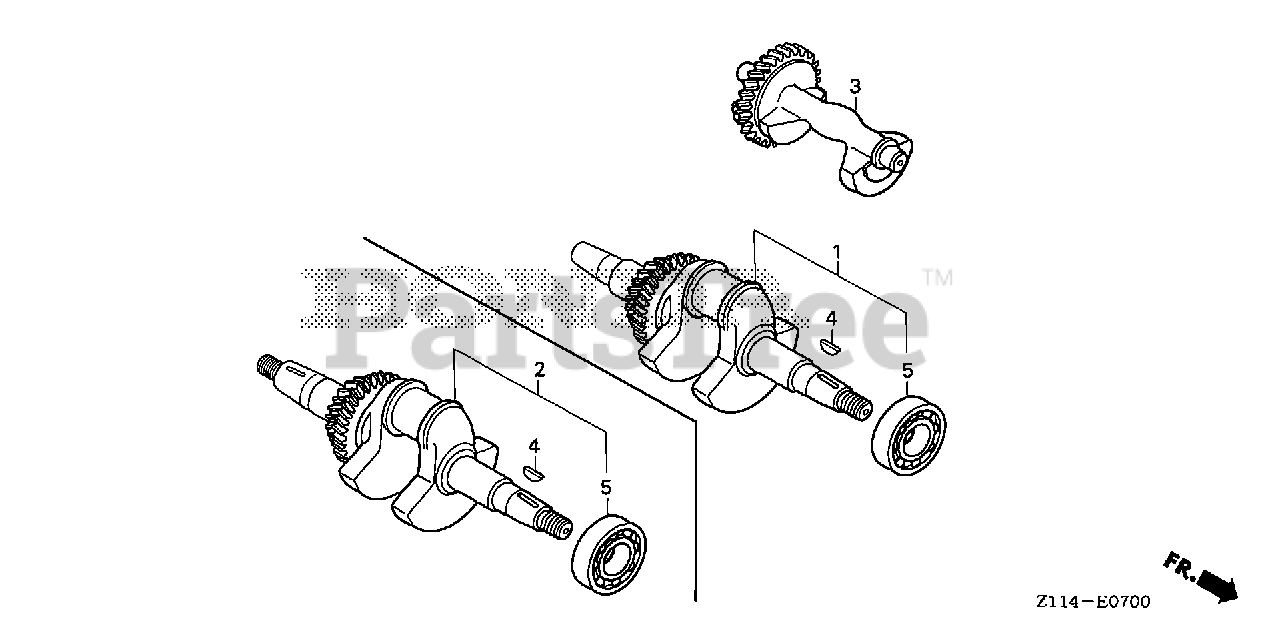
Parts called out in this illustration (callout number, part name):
1	CRANKSHAFT
3	WEIGHT, BALANCER
4	KEY, SPECIAL WOODRUFF (25X18)
5	BEARING, RADIAL BALL (6207)
